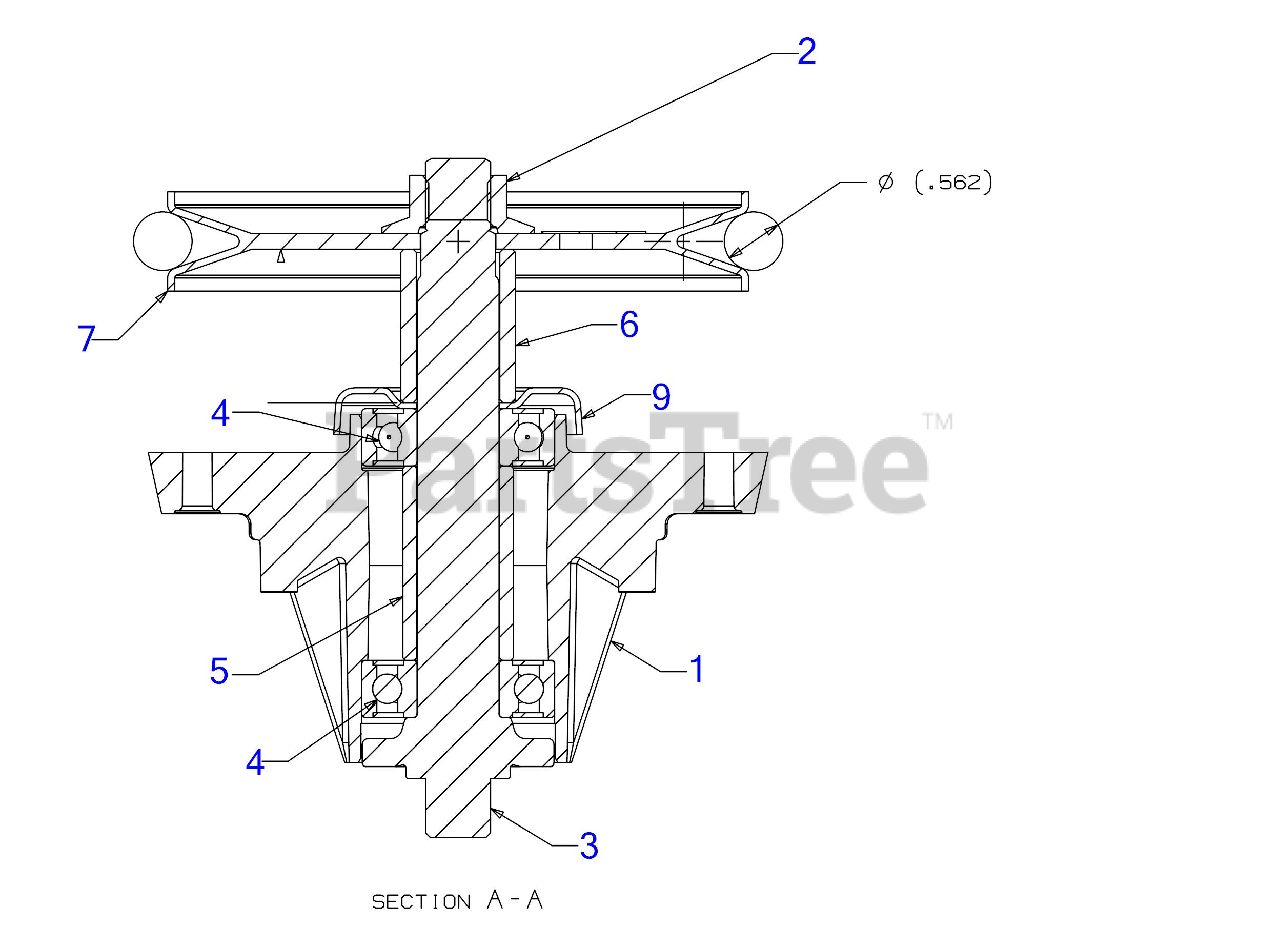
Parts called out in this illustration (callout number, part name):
1	DECK SPINDLE HOUSING
2	FLANGE NUT 5/8-18
3	SPINDLE SHAFT STAR 5.83 LG
4	BALL BEARING
5	SPACER- .792 x 1.060 x 1.860
6	SPACER .800 x 1.100 x 1.470 LG
7	DECK PULLEY 5.4" DIA
9	SHIELD-BRG DECK
